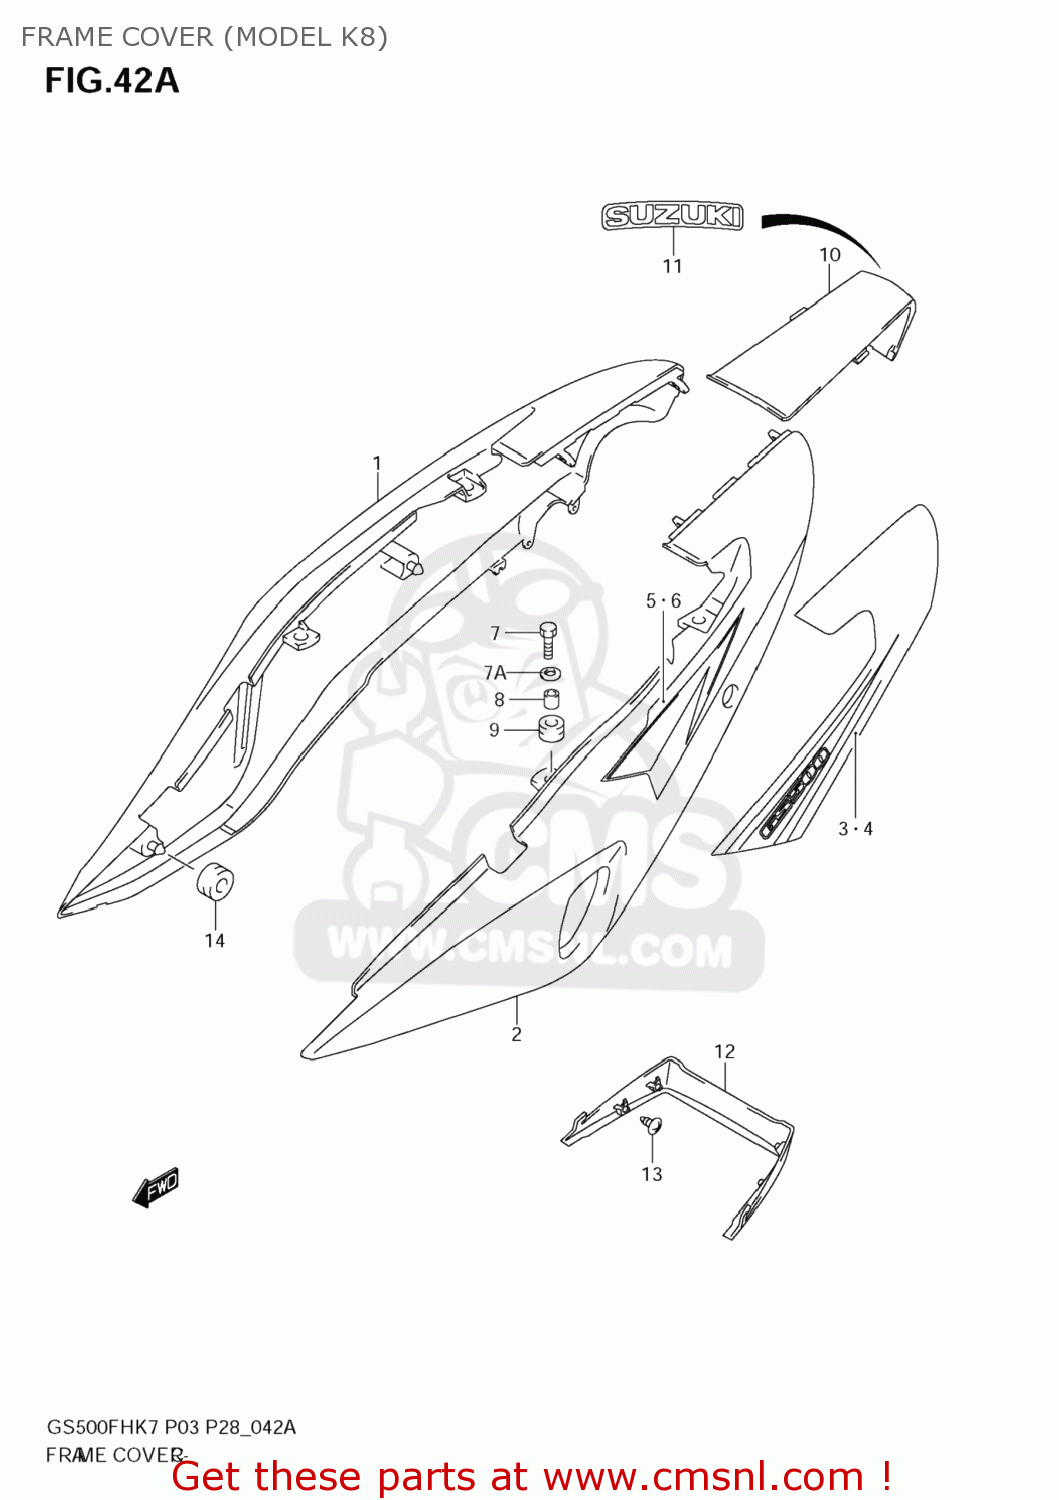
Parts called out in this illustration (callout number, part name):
1	COVER,FRAME RH
2	COVER, FRAME G
3	TAPE,FRAME COVE
4	TAPE,FRONT COVE
5	TAPE, RH
6	TAPE, LH
7	BOLT
7A	WASHER
8	SPACER(6.5X9X9)
9	CUSHION
10	FAIRING PART
11	TAPE,FRAME COVE
12	COVER, LOWER
13	SCREW
14	CUSHION
